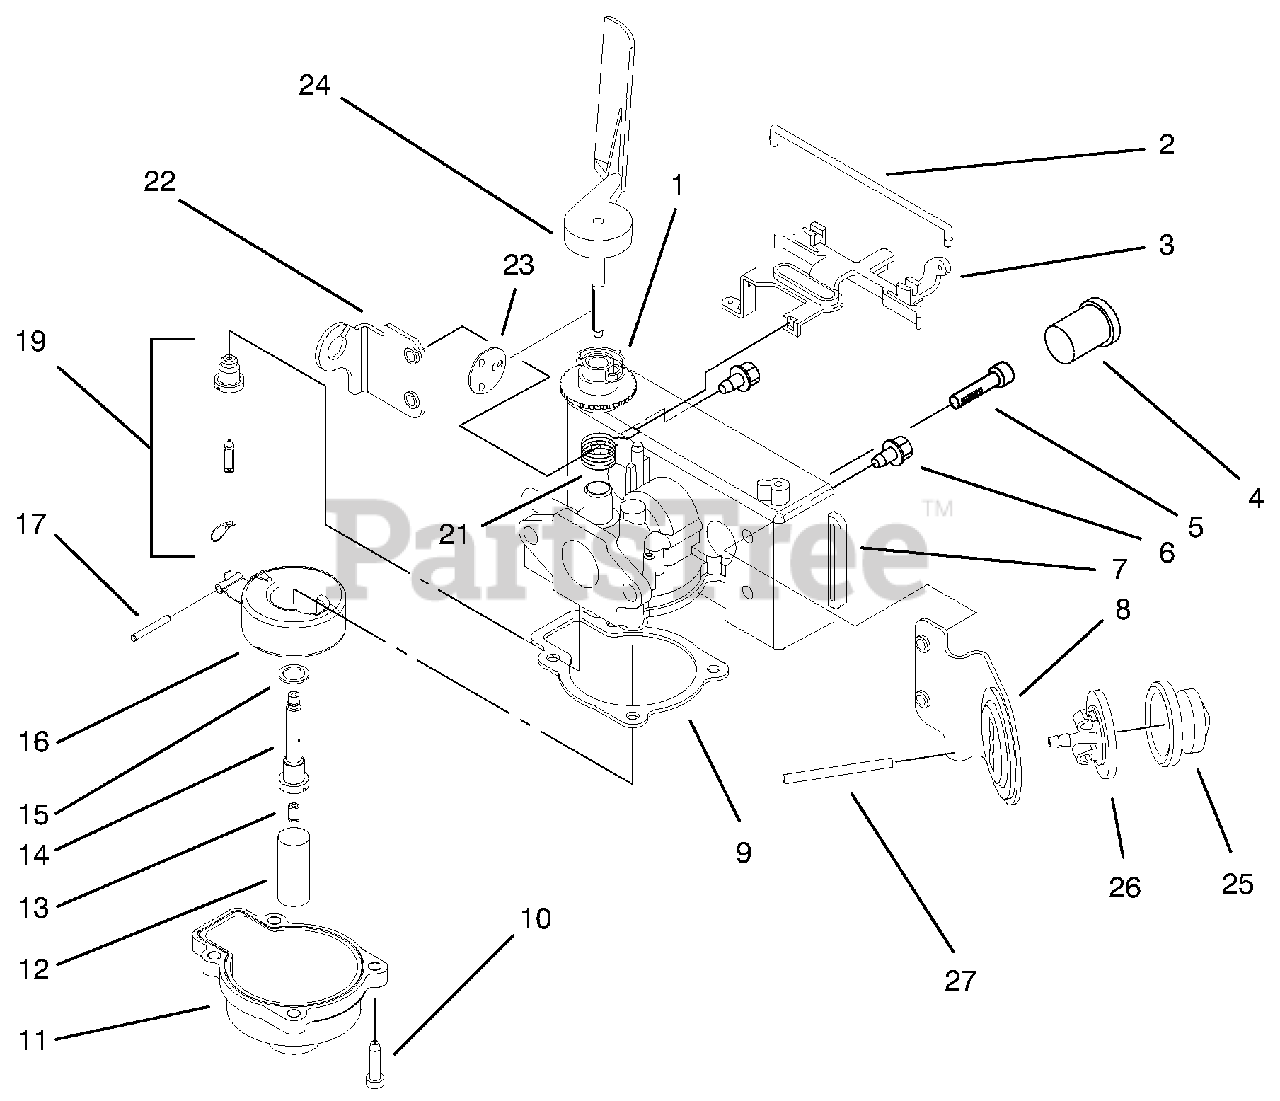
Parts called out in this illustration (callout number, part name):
1	Collar-Adjustment
2	Retainer
3	Lever-Speed Adjsut
4	Plug
5	Screw-Pan Hd. Sems
7	Body-Carburetor
8	Bracket-Primer
9	Gasket-Float Chamber
11	Float Chamber
12	Filter-Fuel
13	Main Jet
16	Float & Arm Assembly
19	Float, Valve, & Body Ass'y
21	Spring-Governor
22	Bracket-Throttle Control
23	Disc-Throttle
24	Air Vane & Shaft
25	Bulb-Primer
26	Body-Primer
27	Hose-Primer
